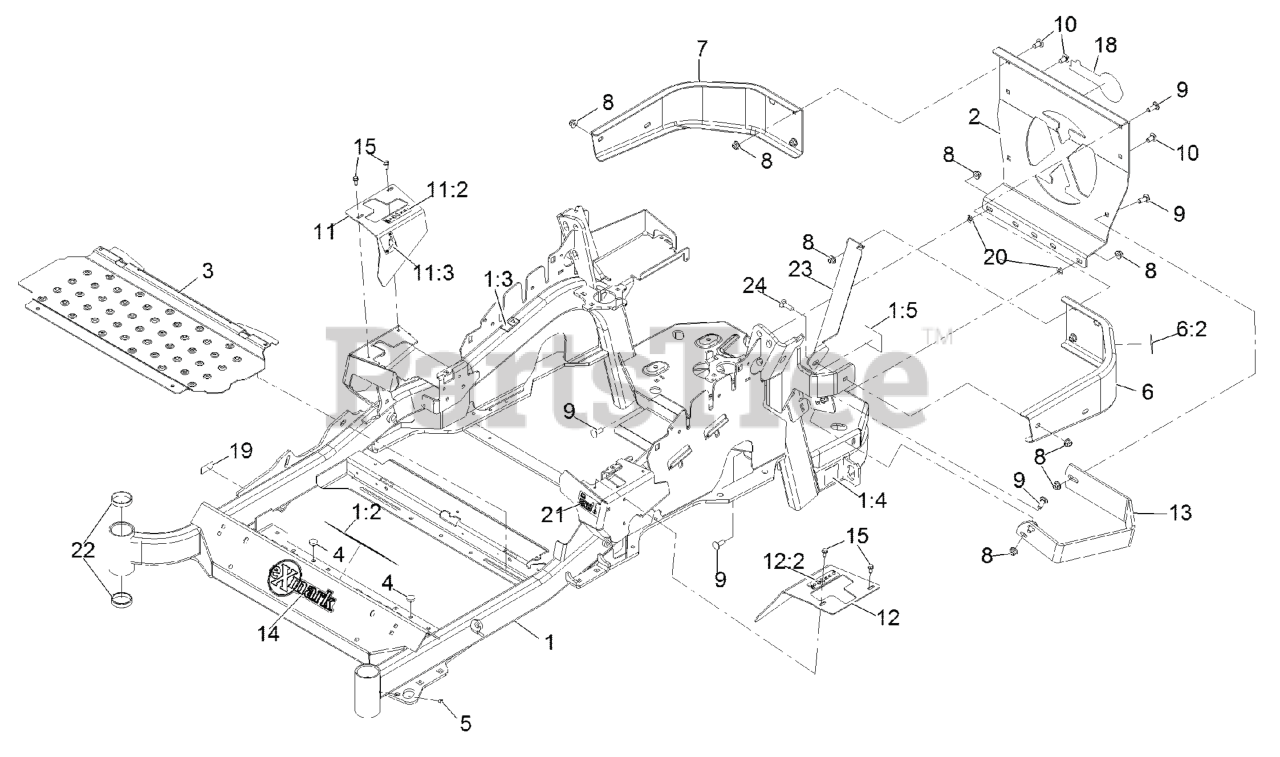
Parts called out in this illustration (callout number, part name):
1	MAINFRAME ASM
1:2	DECAL-DANGER
1:3	DECAL-WARNING
1:4	DECAL-HAZARD, PINCHED FINGER
1:5	DECAL-SPARK ARRESTER
2	PLATE,REAR GUARD
6	LH BUMPER ASM
6:2	DECAL-WARNING
7	BUMPER-RH
8	NUT-HF, NI
9	SCREW-CARR
10	SCREW-CARR
11	RH MOTION CONTROL COVER ASM
11:2	DECAL-CONTROL, MOTION
11:3	DECAL-PARK BRAKE, CE
12	LH MOTION CONTROL COVER ASM
12:2	DECAL-CONTROL, MOTION
13	GUARD-MUFFLER
14	DECAL-EXMARK LOGO
15	SCREW-HWH
18	DECAL-EXMARK LOGO
19	Decal-Patent Ttco.Com
20	NUT-PUSH
21	DECAL-FUEL FILL, CE
22	CUP-BEARING
24	BOLT-CARR
